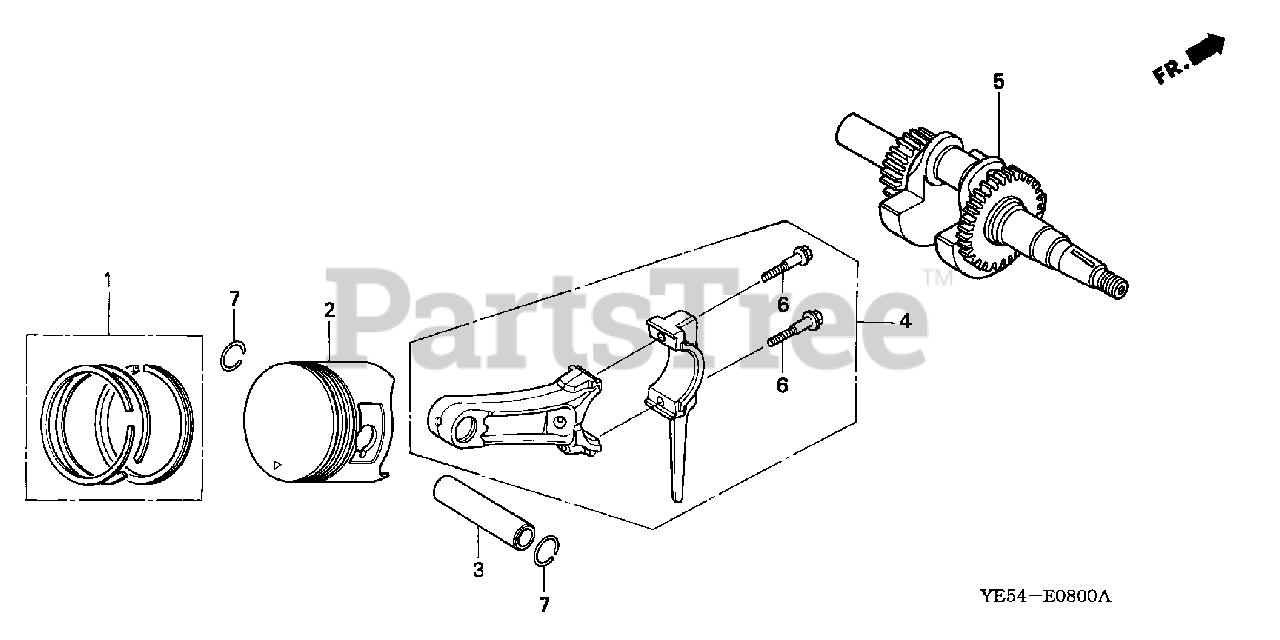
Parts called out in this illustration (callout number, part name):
1	RING SET, PISTON (STD) (TEIKOKU)
1	RING SET, PISTON (STD) (NIPPON)
1	RING SET, PISTON (OS 0.25) (TEIKOKU)
1	RING SET, PISTON (OS 0.25) (NIPPON)
1	RING SET, PISTON (OS 0.50) (TEIKOKU)
1	RING SET, PISTON (OS 0.50) (NIPPON)
1	RING SET, PISTON (0.75) (TEIKOKU)
1	RING SET, PISTON (0.75) (NIPPON)
2	PISTON (STD)
2	PISTON (OS 0.25)
2	PISTON (OS 0.50)
2	PISTON (0.75)
3	PIN, PISTON
4	ROD ASSY., CONNECTING
5	CRANKSHAFT (W-TYPE)
6	BOLT, CONNECTING ROD
7	CLIP, PISTON PIN (13MM)
